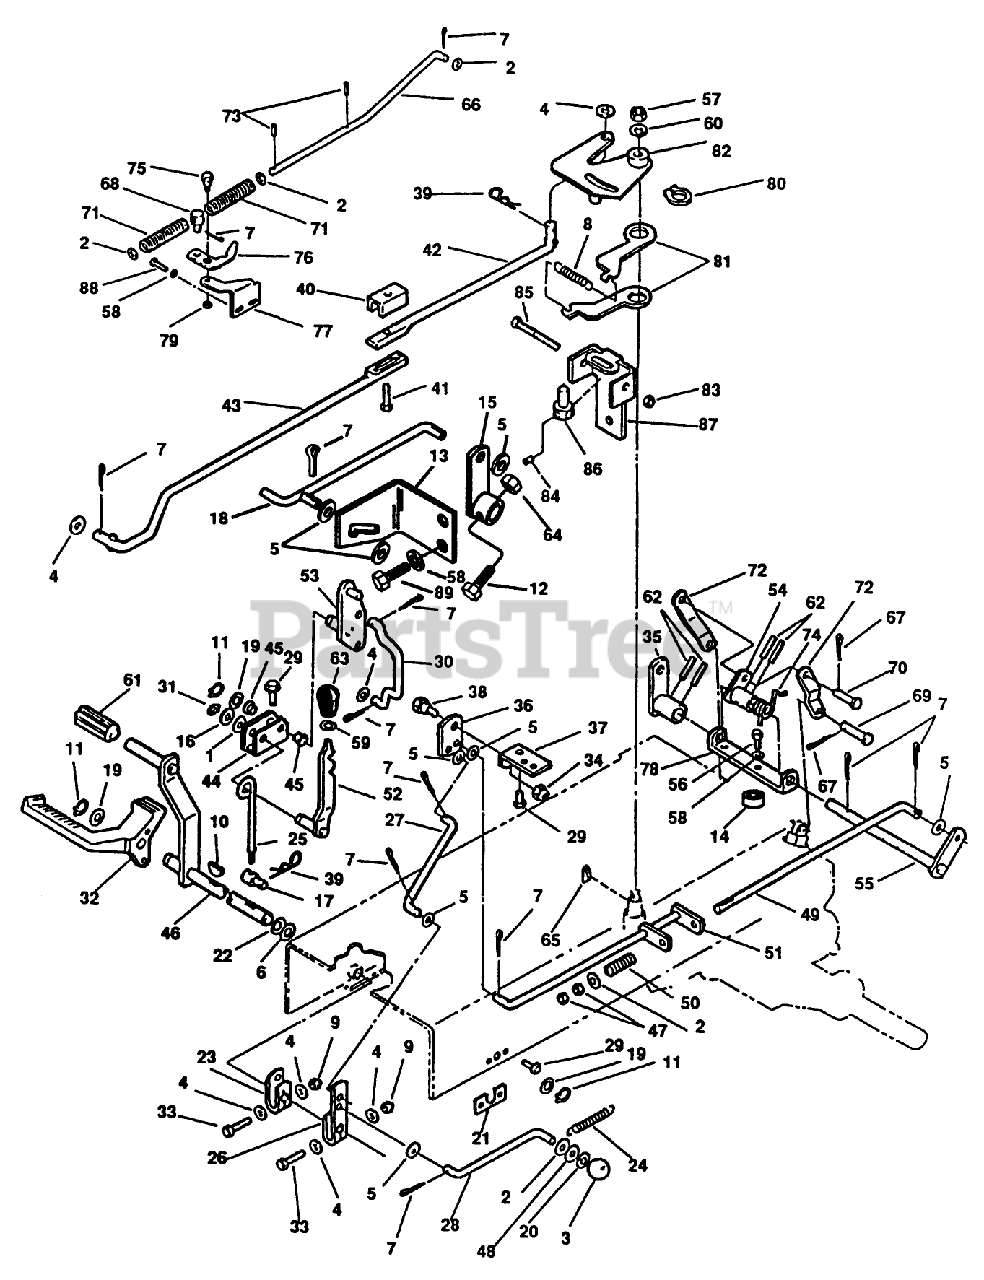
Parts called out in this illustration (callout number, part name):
8	SPRING-EXTENSION
9	NUT-LOCKING
22	WASHER-CUPPED
31	RING - RETAINING
37	BRKT-BRAKE PIVOT
39	PIN-HAIR
49	LINK-BRAKE SPRING
52	CRUISE RELEASE AY.
56	SCREW - HEX
72	PLATE - BRAKE CLEVIS
74	SPRING,TORSION
75	BOLT-SHOULDER
77	BRACKET-LOCK
78	BRACKET
80	RING - RETAINING
84	SETSCREW
89	SCREW-THD ROLL, HWH
